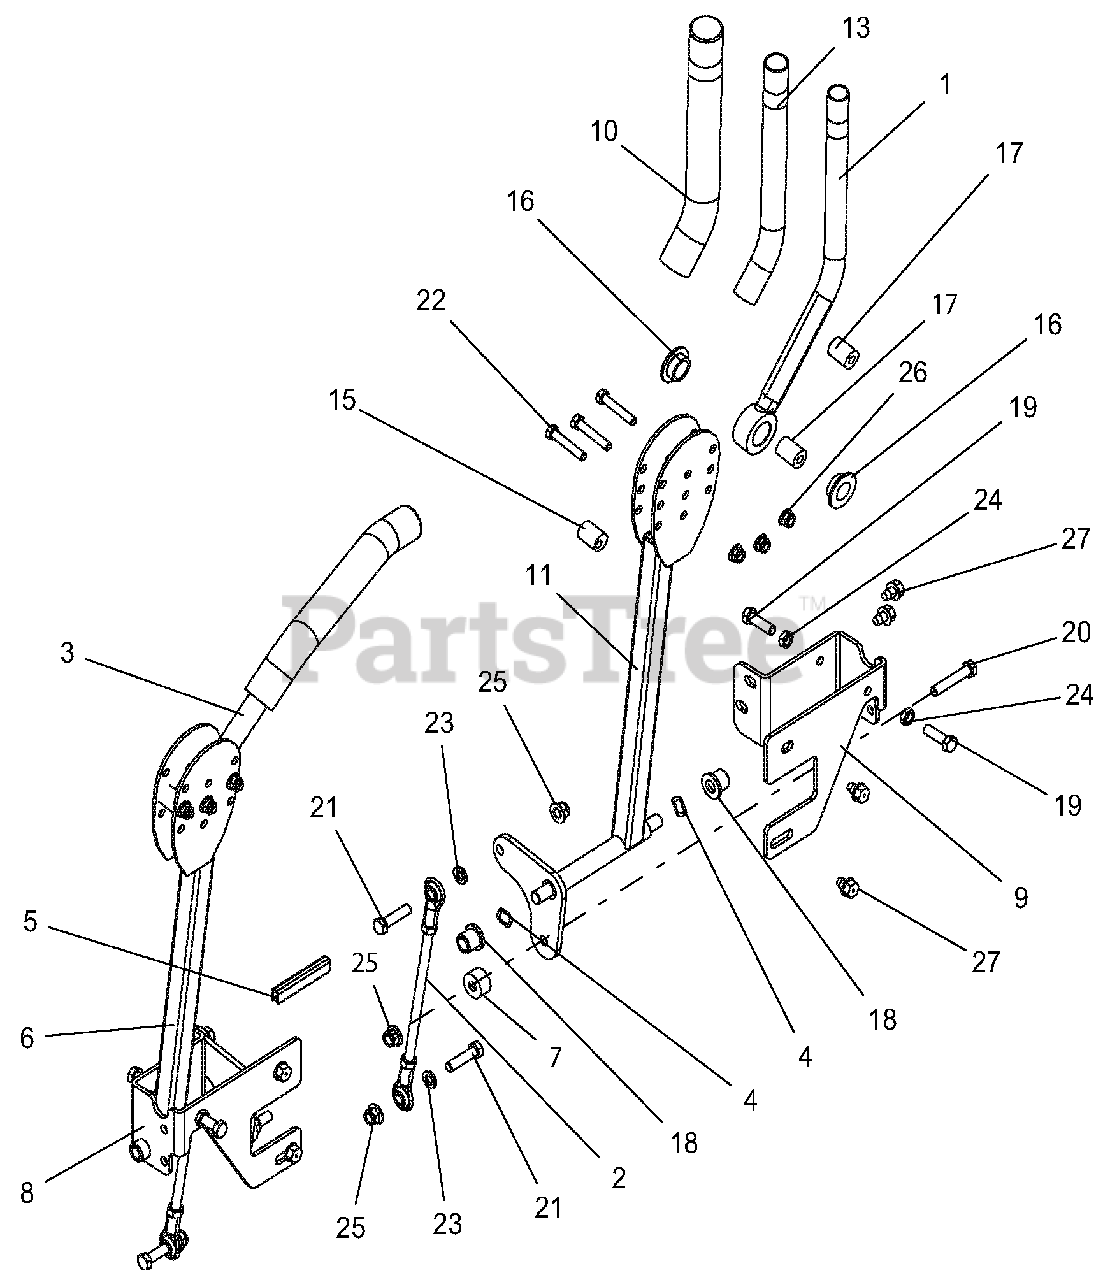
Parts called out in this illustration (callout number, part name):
1	WLDMT, LH HANDLE
2	ASM, STEERING LINKAGE
3	WLDMT, RH HANDLE
4	WAVE WASHER .531X.781X.125 FH
5	STRIP, COWL - 1.50 LG
6	WLDMT, PT/PT100 CONTROL ARM-BLACK
7	SPACER .390X1.000X.562
8	BRKT, RH STEERING STOP-RED
9	BRKT, LH STEERING STOP-RED
10	GRIP, HANDLEBAR
11	WLDMT, LH PT/PT100 CONTROL ARM
13	TUBE, .88ID X 1.00OD X 10.25
15	BSHG, ECCENTRIC .31 X .775 X .9
16	BSHG, FLANGE .762 X 1.48 X .44 NYLON
17	SPACER, .328 X .76 X 1.01
18	BHSG-FLG .500X.750X.750X.125
19	BLT-HEX .38-16X1.25 GR5 YWZC
20	BLT-HEX .38-16X2.00 FTH GR5 YWZC
21	BLT-HEX .38-16X1.50 GR5 YWZC
22	BLT-HEX .31-18X1.75 GR5 YWZC
23	WSHR-LK .38X.094 REG YWZC
24	NUT, JAM .375-16 YWZC
25	NUT-LK-NYL-FLG .38-16 YWZC
26	NUT-LK-NYL-FLG .31-18 YWZC
27	SCR-TAP .38-16X.50 HWH TR YWZ
